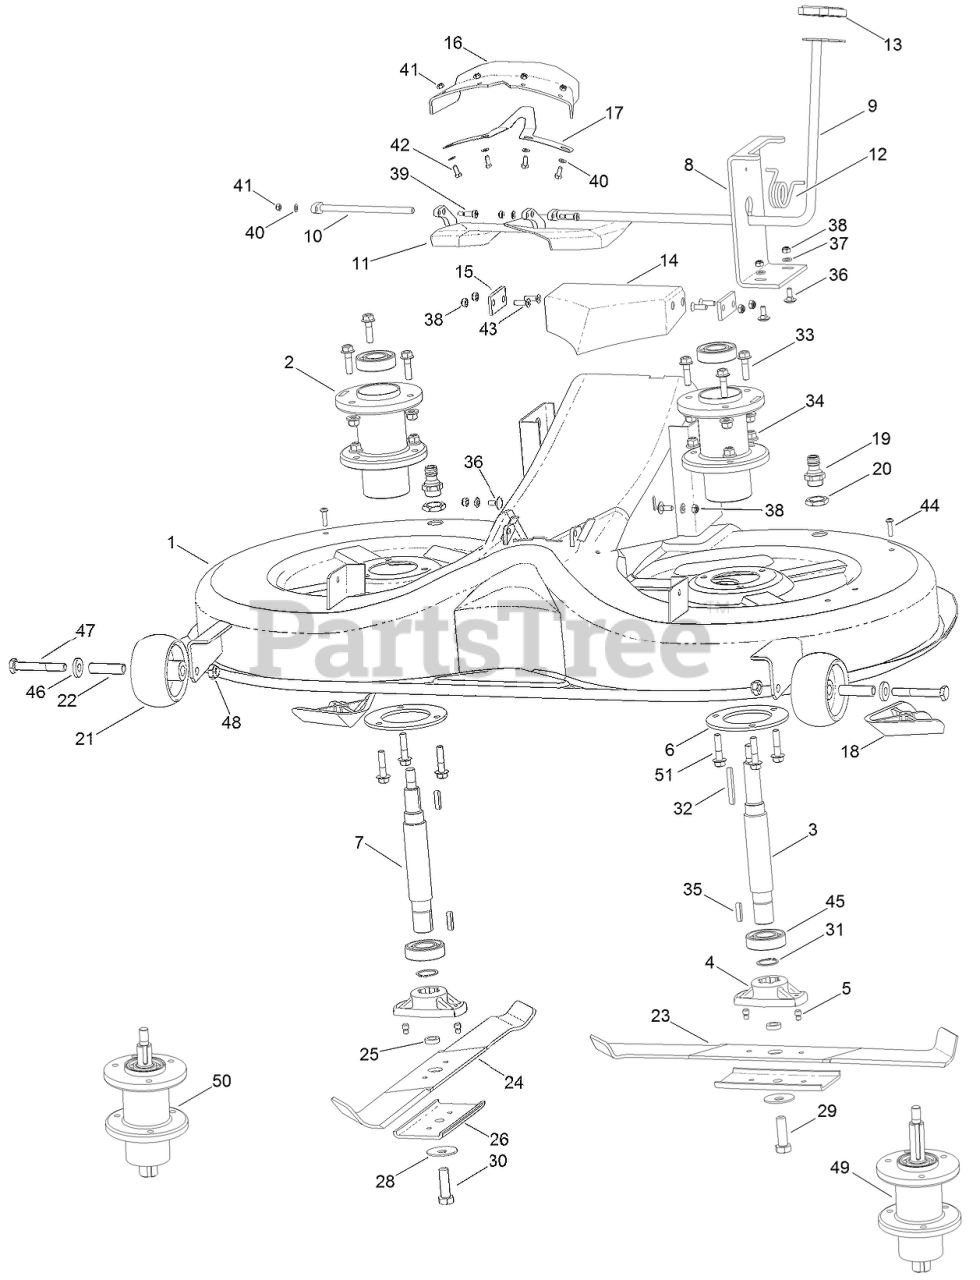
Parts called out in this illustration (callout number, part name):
1	DECK ASM WITH DECALS
2	HOUSING-SPINDLE
3	SHAFT-BLADE, LEFT
4	Adapter-Blade
5	PIN-SHEAR, GROOVED
6	SUPPORT-RING
7	Shaft-BLADE, Right
8	HOLDER
9	LEVER-FOOT
10	Rod-Door, Mulch
11	DOOR-MULCH
12	SPRING
13	PAD-PEDAL
14	Baffle-Center
15	PLATE-BAFFLE, CENTER
16	Gasket-Door, Mulch
18	Kicker
19	CONNECTION
21	WHEEL-GAUGE
22	SPACER
23	BLADE-LH
24	BLADE-RH
25	Spacer
26	STIFFENER-BLADE
28	WASHER-BLADE
29	BOLT-HH
30	BOLT-BLADE, HH
31	RING-LOCKING
33	SCREW-HHF
34	NUT-LOCK, HHF
35	KEY-SQUARE
36	SCREW-CARR
37	WASHER
38	NUT-LOCK
40	WASHER
41	NUT-LOCK
44	SCREW-TAP, PPH
45	BEARING-BALL
46	WASHER-FLAT
47	SCREW-HH
48	NUT-LOCK, NI
49	LH SPINDLE HOUSING ASM
50	RH SPINDLE HOUSING ASM
51	BOLT-HHF
